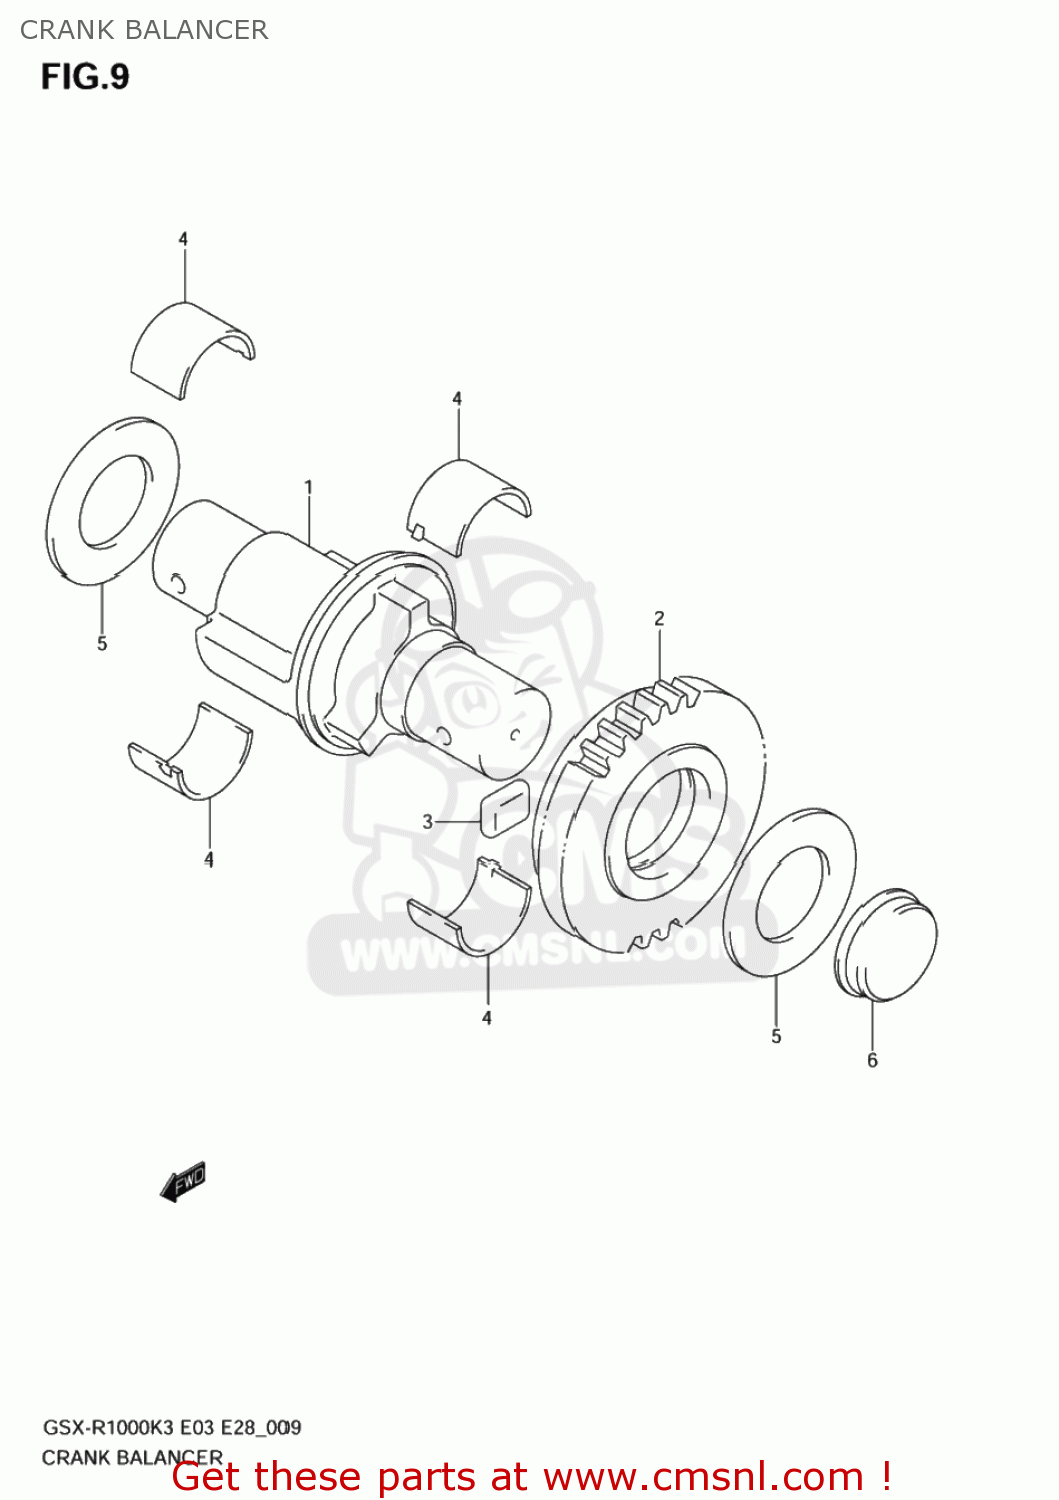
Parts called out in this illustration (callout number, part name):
1	BALANCER,CRANK
2	GEAR,CRANK BALANCER
3	DAMPER,CRANK BALANCER GEAR
4	BEARING,CRANK BALANCER
5	SHIM(23X40X2)
6	PLUG
